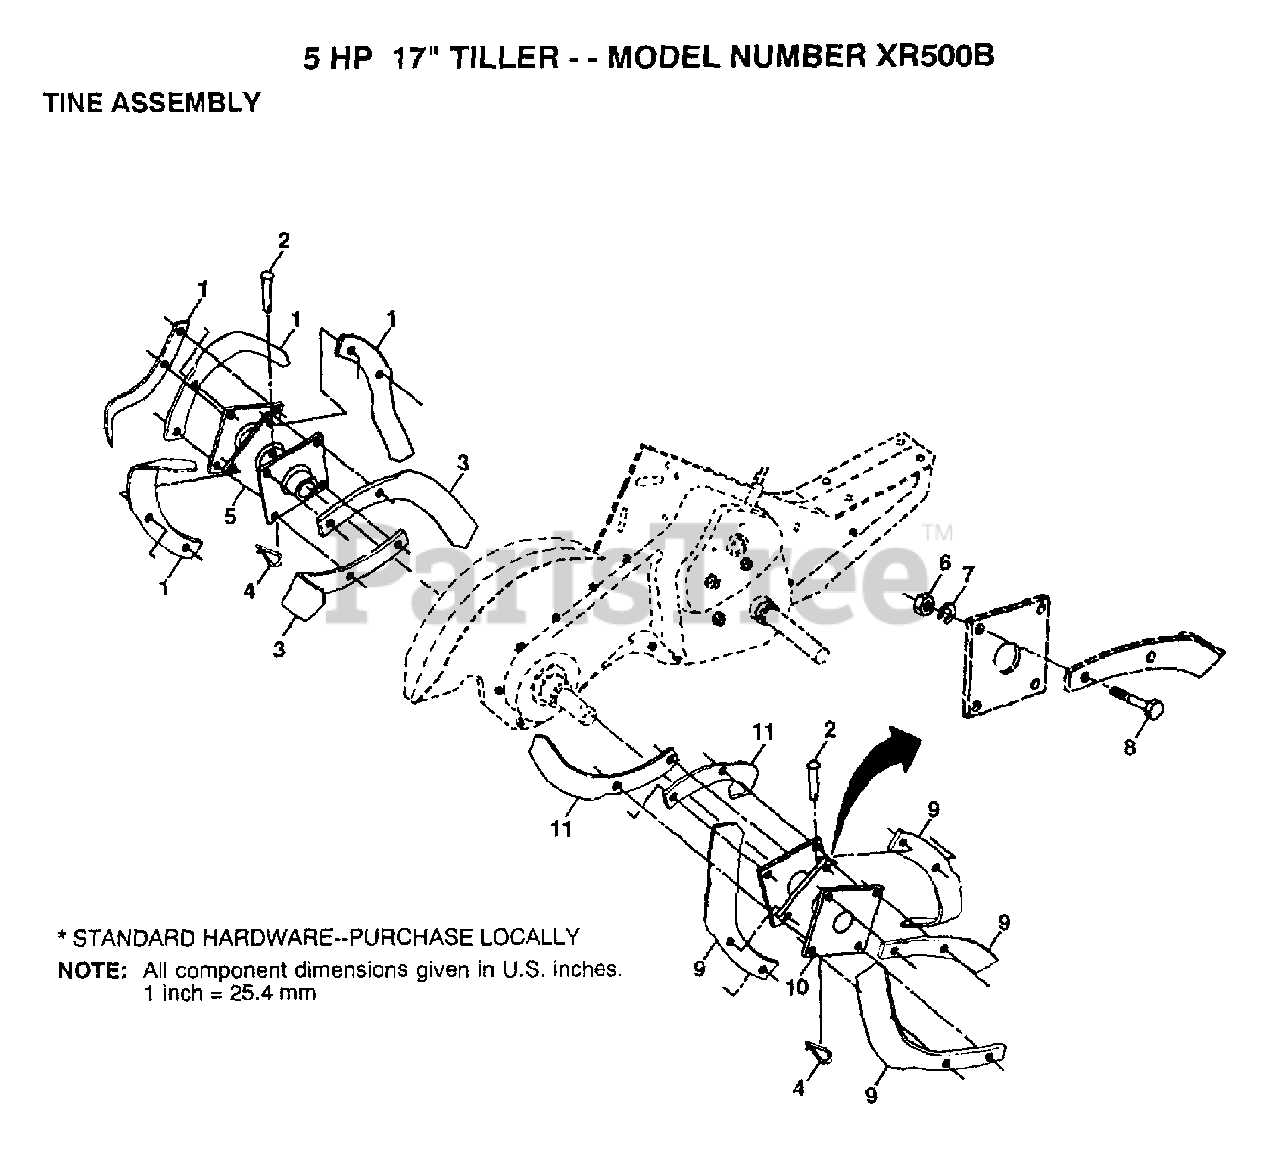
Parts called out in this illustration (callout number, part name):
2	PIN.CLEVIS.SHEAR
3	"TINE.LH.12"""
4	RETAINER.SPRING
5	HUB&PLATE ASM LH
7	LOCKWASHER
8	BOLT
10	HUB&PLATE ASM RH
11	"TINE.RH.12"""
